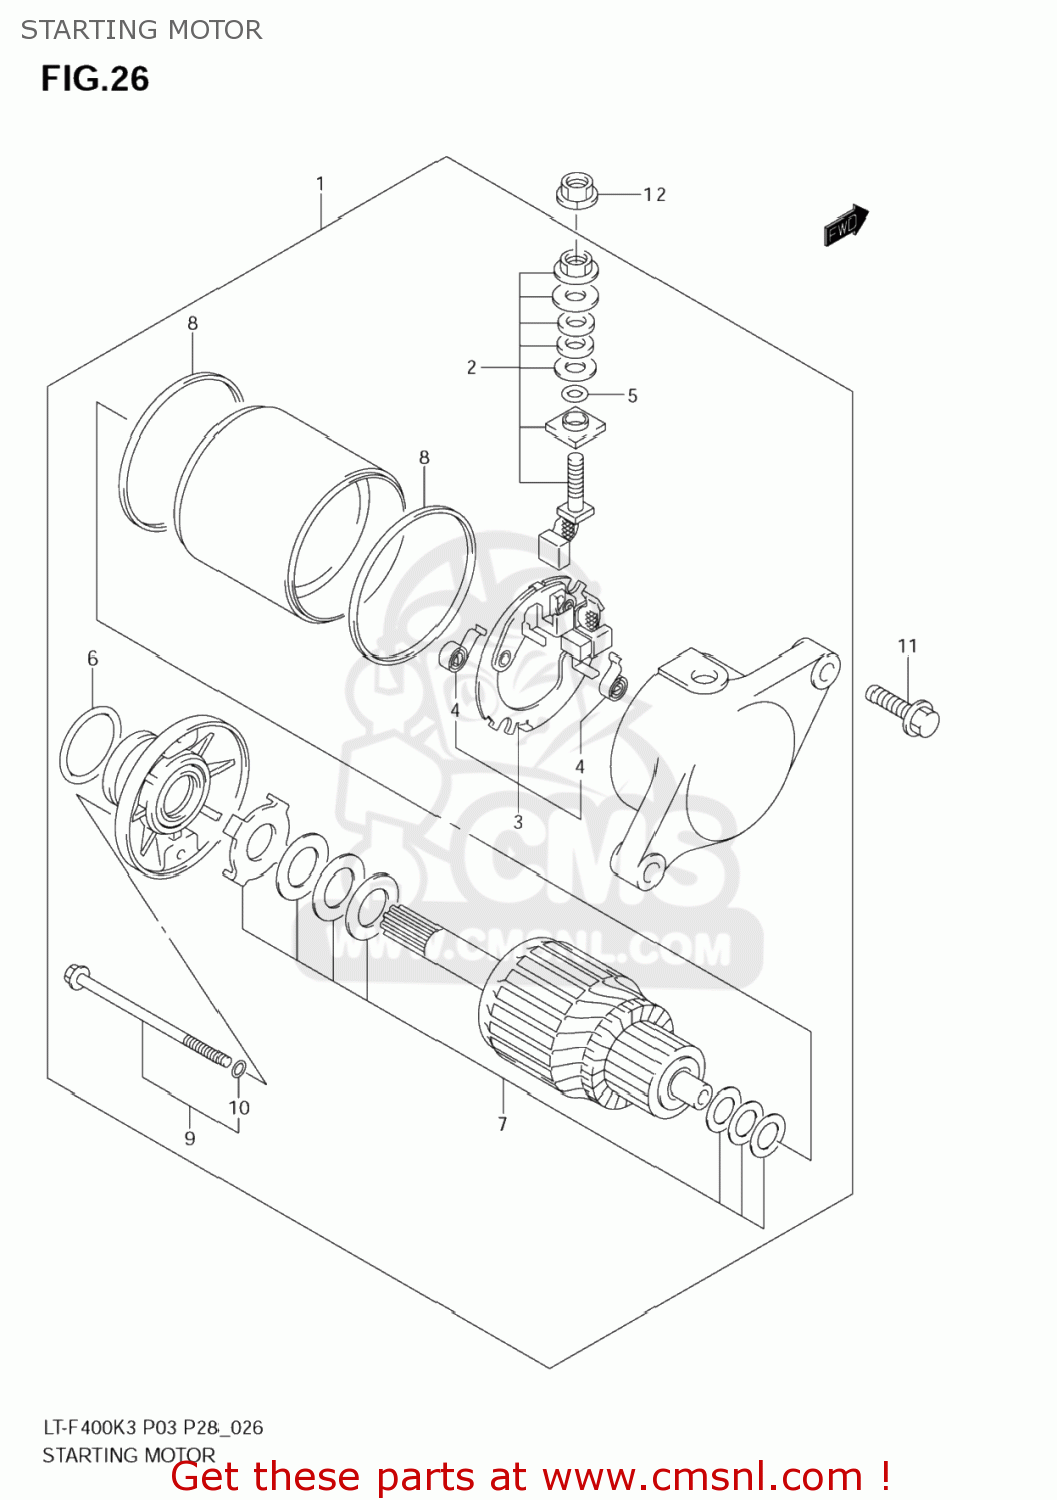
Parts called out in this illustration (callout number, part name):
1	MOTOR ASSY,STARTING
2	BRUSH TERMINAL SET
3	BRUSH HOLDER SET
4	SPRING,BRUSH
5	O RING
6	O RING(D:3,ID:24.5)
7	SHIM SET,STARTING MOTOR
8	O RING
9	BOLT
10	O RING
11	SCREW
12	NUT
